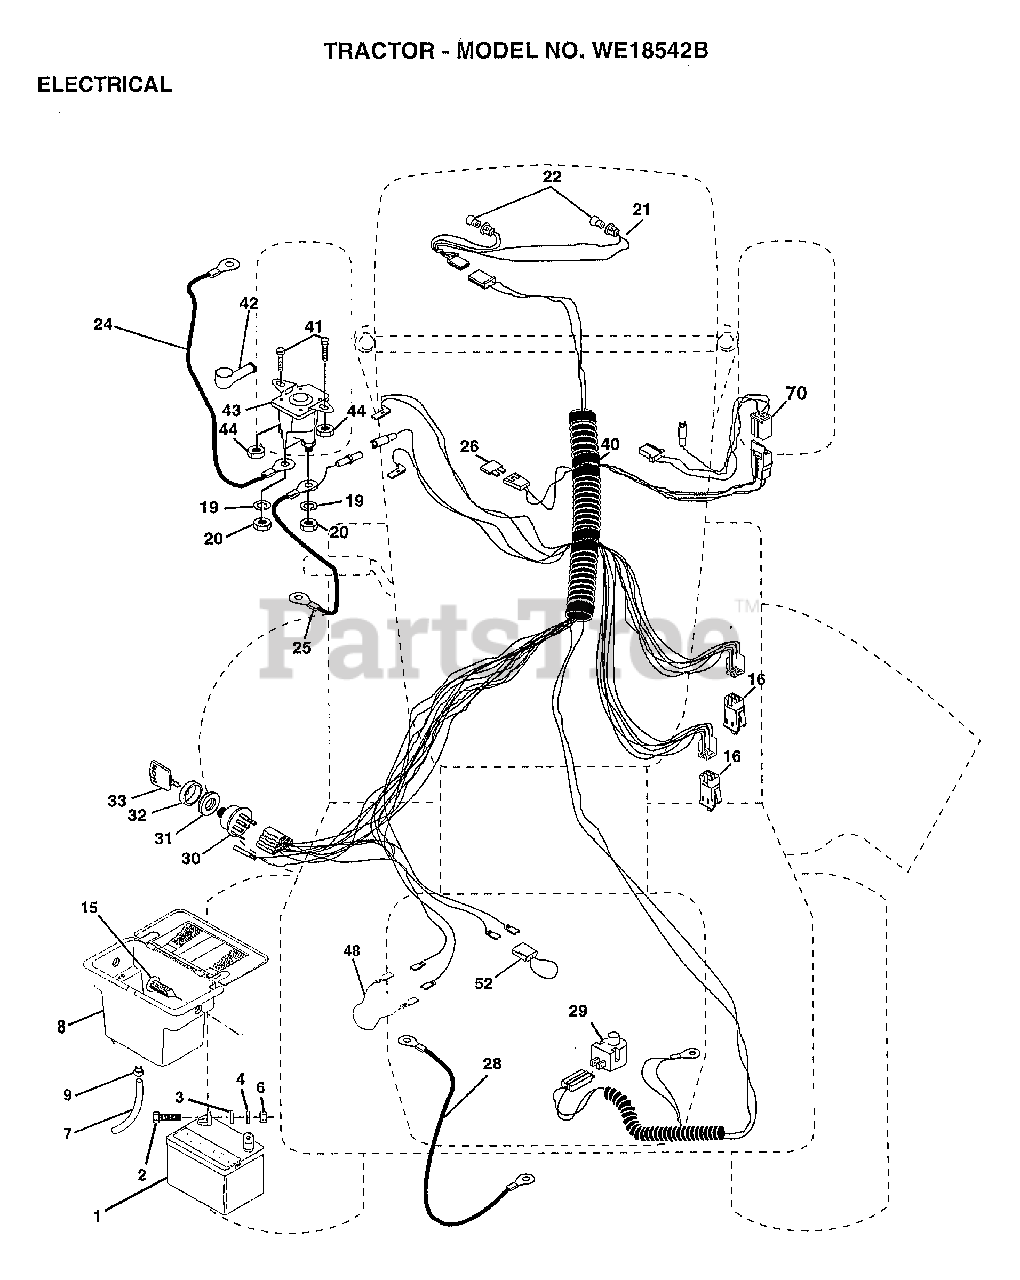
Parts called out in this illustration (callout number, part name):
2	BOLT LT
3	WASHER
4	LOCKWASHER
7	TUBE T
8	"CASE,BATTERY.MECH"
9	HOSE CLAMP T
15	FASTNER.SNAP-IN
16	SWITCH INTERLOCK
20	NUT
21	"HARNESS,LIGHT SOC"
22	HEADLAMP BULB
24	"CABLE T, BATTERY"
25	CABLE.BTRY.6GA.RD
26	FUSE HYT
28	CABLE T
29	SWITCH SEAT
30	SWITCH IGN 4POS
31	NUT IGNITION
32	COVER KEY SWITCH
33	KEY
40	HARNESS-IGNITION
41	BOLT HXHD FIN
44	NUT HXKEP 1/4X20
48	ADAPTER AMMETER
52	PROTECTION LOOP
70	HARNESS ENG DUAL
